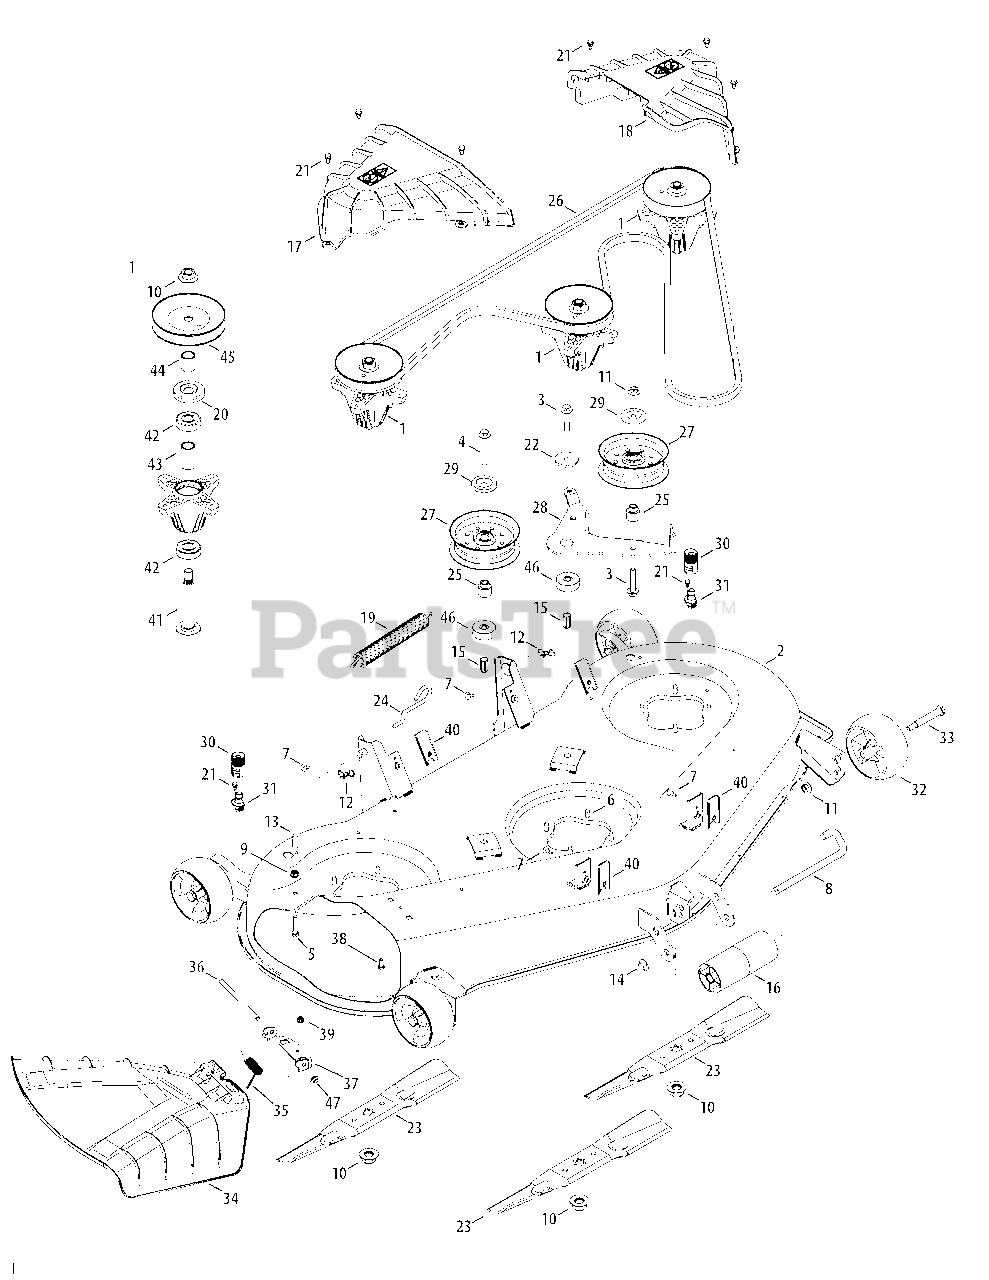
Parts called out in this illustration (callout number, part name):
1	Spindle Ass’y, Pulley, 5.37 Dia
2	Deck, 54"
3	Hex Cap Screw, 3/8-16 x 2.00
4	Hex Cap Screw, 3/8-16 x 2.75
5	Hex Cap Screw, 5/16-18 x 1.50
6	Screw, Self-tapping, 5/16-18, 0.750,
7	Screw, M6-1 x .625
8	Roller Pin, 1/2 x 7.31 Lg
9	Nut, Flange Lock, 5/16-18, Nylon
10	Nut, Flange, 5/8-18
11	Flange Lock Nut, 3/8-16
12	Bow-Tie Cotter Pin
13	Vinyl Cap, .29 x 1.00
14	Push Cap, 1/2"
15	Rivet Nut, 3/8-16
16	Front Roller
17	Belt Cover, RH
18	Belt Cover, LH
19	Spring, Extension, 1.25 OD x 8.5
20	Bearing Shield
21	Shoulder Screw, 1/4-20 x 0.50
22	Shoulder Spacer, .970 x .190
23	Blade, Cut, 18.67" 2-In-1
24	Deck Spring Rod
25	Shoulder Spacer
26	Belt, V-Type, B Sec x 139
27	Pulley, Idler, 4.50" Dia.
29	Pulley Cap
30	Coupler, Water
31	Deck Wash Nozzle
32	Wheel, Deck, 5.0 Dia. Ball
33	Bolt, Shoulder, .496 x 2.50, 3/8-16
34	Chute Deflector Assembly
35	Spring, Torsion, .440 ID x 1.75
38	Hex Cap Screw, 1/4-20 x .62
39	Nut, Flange Lock, 1/4-20, Nylon
40	Bracket, Lift, Stop
41	Shaft, Spindle, 6.11
42	Bearing, Ball, .787id x 1.85 Od x .551
43	Spacer, .792 x 1.060 x 1.860
44	Spacer, .792 x 1.060 x 1.782
45	Pulley, Deck, 4.50 Dia.
46	Spacer, .385 ID x 1.75 OD x .585
47	Push Cap
